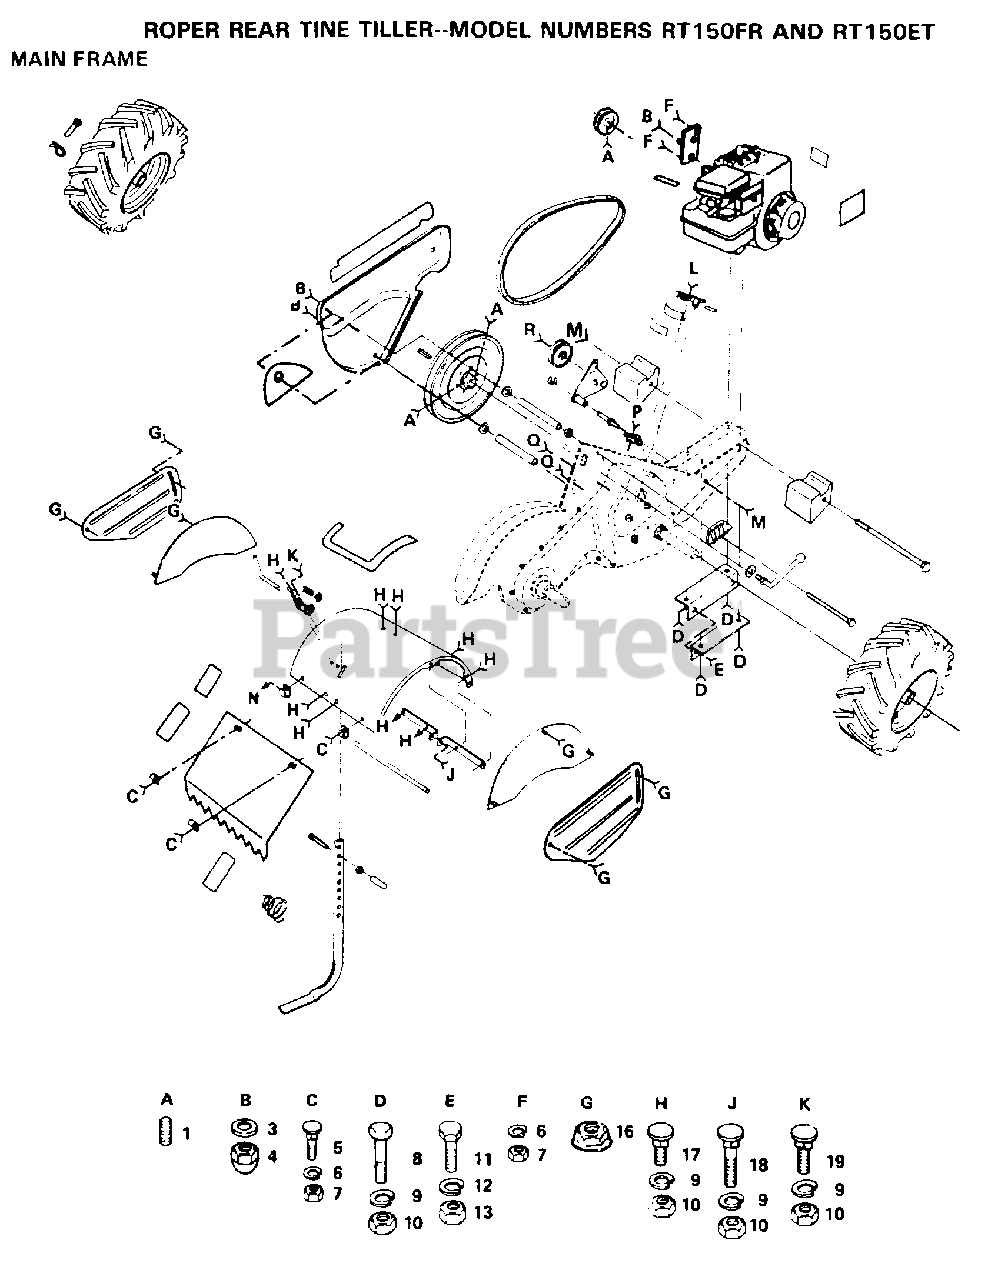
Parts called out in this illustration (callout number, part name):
1	SET SCREW
3	WASHER
4	NUT TI
5	BOLT
6	LOCKWASHER
8	BOLT.HEX.5/16-1.5
9	LOCKWASHER
10	NUT.HEX.5/16-18
11	BOLT
12	LOCKWASHER
13	NUT.HEX.3/8-16UNC
16	NUT
17	BOLT
18	BOLT CRT
19	BOLT
